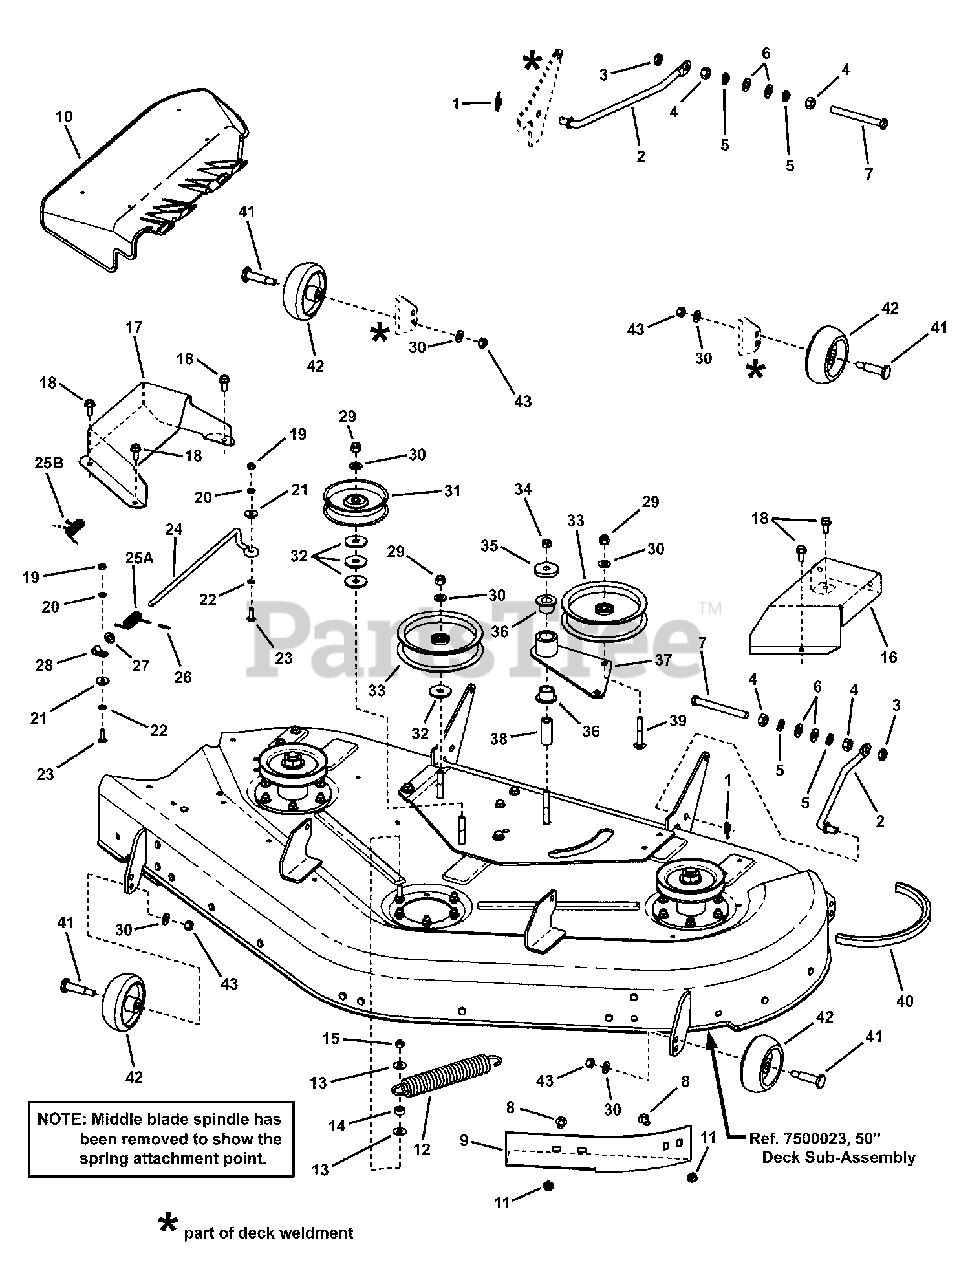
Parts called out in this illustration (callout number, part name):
1	COTTER PIN, 1/2 Self Locking, YZ
2	ROD, Stabilizer
3	NUT, 7/16-20 Hex Center Lock Jam, GR 5 or B
4	NUT, 7/16-20 Hex, GR 5 or B
5	WASHER, 7/16" Split Lock
6	WASHER, .47 x .92 x .065 Flat
7	SCREW, 7/16-20 x 4" Hex Head Cap, GR 5
8	BOLT, 5/16-18 x 3/4" Short Neck Carriage, GR 5
9	BAFFLE, Anti-Blowout
10	DEFLECTOR, Black Plastic
11	NUT, 5/16-18 Hex Flange Lock, GR 5
12	SPRING, Idler, 44/50" Deck
13	WASHER, 3/8" Flat
14	SPACER, .340 I.D. x .63 O.D. x .310 Thick
15	NUT, 5/16-18 Hex Center Lock, GR 5 or B, YZ
16	COVER, Spindle, LH, Red, RZT 44/50"
17	COVER, Spindle, RH, Red, RZT 44/50"
18	SCREW, 5/16-18 x 3/4" Hex Washer Self-Tap
19	NUT, 1/4-20 Hex
20	LOCKWASHER, 1/4" Spring
21	WASHER, Large 1/4 ID x 5/8 OD x .134/.109
22	RETAINER, 1/4" Bolt
23	BOLT, 1/4-20 x 7/8" Round Head Short Square Neck Carriage, GR 5
24	ROD, Pivot, Side Discharge, 50" Deck
25A	SPRING, Torsion
25B	SPRING, Torsion, Chute 44/50
26	CAP, Spring End
27	WASHER, .34 ID x .75 OD Flat
28	CLAMP
29	NUT, 3/8-16 Hex Nyloc
30	WASHER, 3/8" Flat SAE
31	PULLEY, 4" Flat Idler
32	WASHER, .406 x 1.50 x .120 Flat
33	PULLEY, Flat Idler 5.0 x .375
34	NUT, Hex Cap Lock 3/8-16
35	WASHER, .468 x 1.625 x .25 Flat
36	BEARING, Powdered Metal
37	WELDMENT, Idler Swing Arm
38	SPACER, Idler (.75 x .390 x 1.800)
39	BOLT, 3/8-16 x 2-1/4" Short Square Neck Carriage, GR 5
40	BELT, B Section, 150" Effective Length
41	SHOULDER BOLT, 3/8-16 x 3/4" YZ
42	WHEEL, 4 x 1-7/8" Offset
43	NUT, 3/8-16 Hex Center Lock
